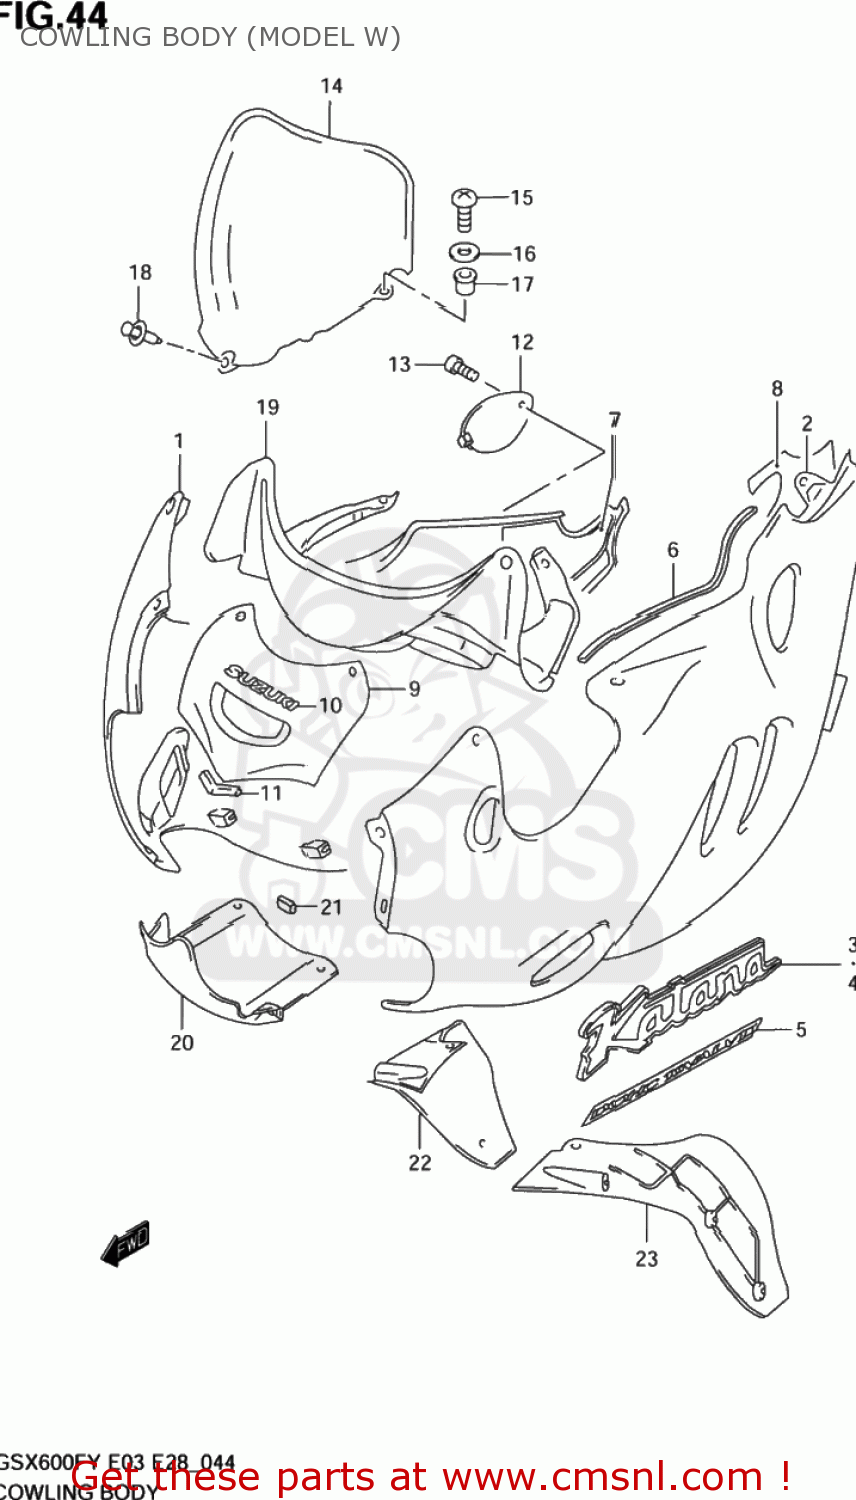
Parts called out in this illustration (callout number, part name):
1	COWLING ASSY,SIDE,R
2	COWLING ASSY,SIDE,L
3	EMBLEM,COWLING SIDE,KATANA,R
4	EMBLEM,COWLING SIDE,KATANA,L
5	EMBLEM,COWLING SIDE
6	MOLD,COWLING
7	SHIELD,COWLING COVER,R
8	SHIELD,COWLING COVER,L
9	PANEL,COWLING CTR UPR
10	EMBLEM,SUZUKI(SILVER)
11	CUSHION,CTR PANEL UPR
12	LID,OIL
13	SCREW(6X16)
14	WINDSCREEN
15	SCREW(5X14)
16	WASHER
17	NUT
18	CLIP(BLACK)
19	PANEL,METER
20	PANEL,COWLING CTR LWR
21	CUSHION,CENTER PANEL,LOWER
22	PANEL,COWLING INNER,R
23	PANEL,COWLING INNER,L
